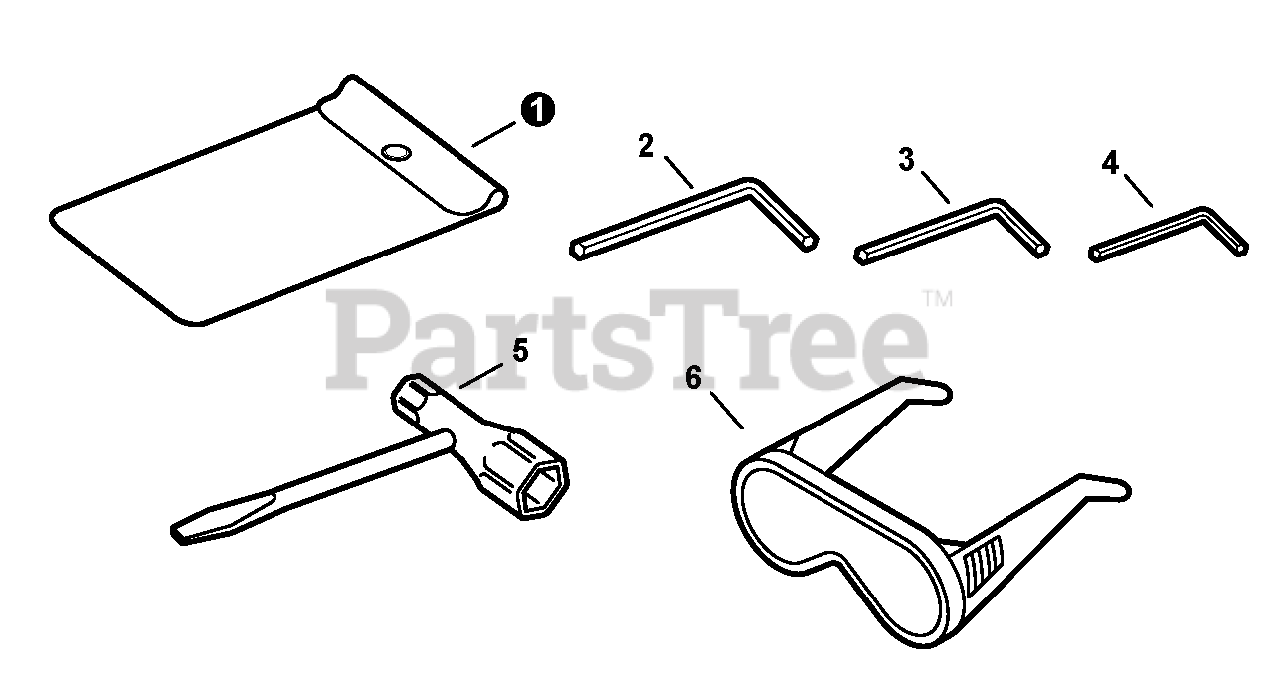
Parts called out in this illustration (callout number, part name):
1	Bag, Tool
2	Wrench, Allen 5mm
3	Wrench, Allen 4mm
4	Wrench, Allen 3mm
5	T-wrench 13x19mm
6	Glasses, Safety
